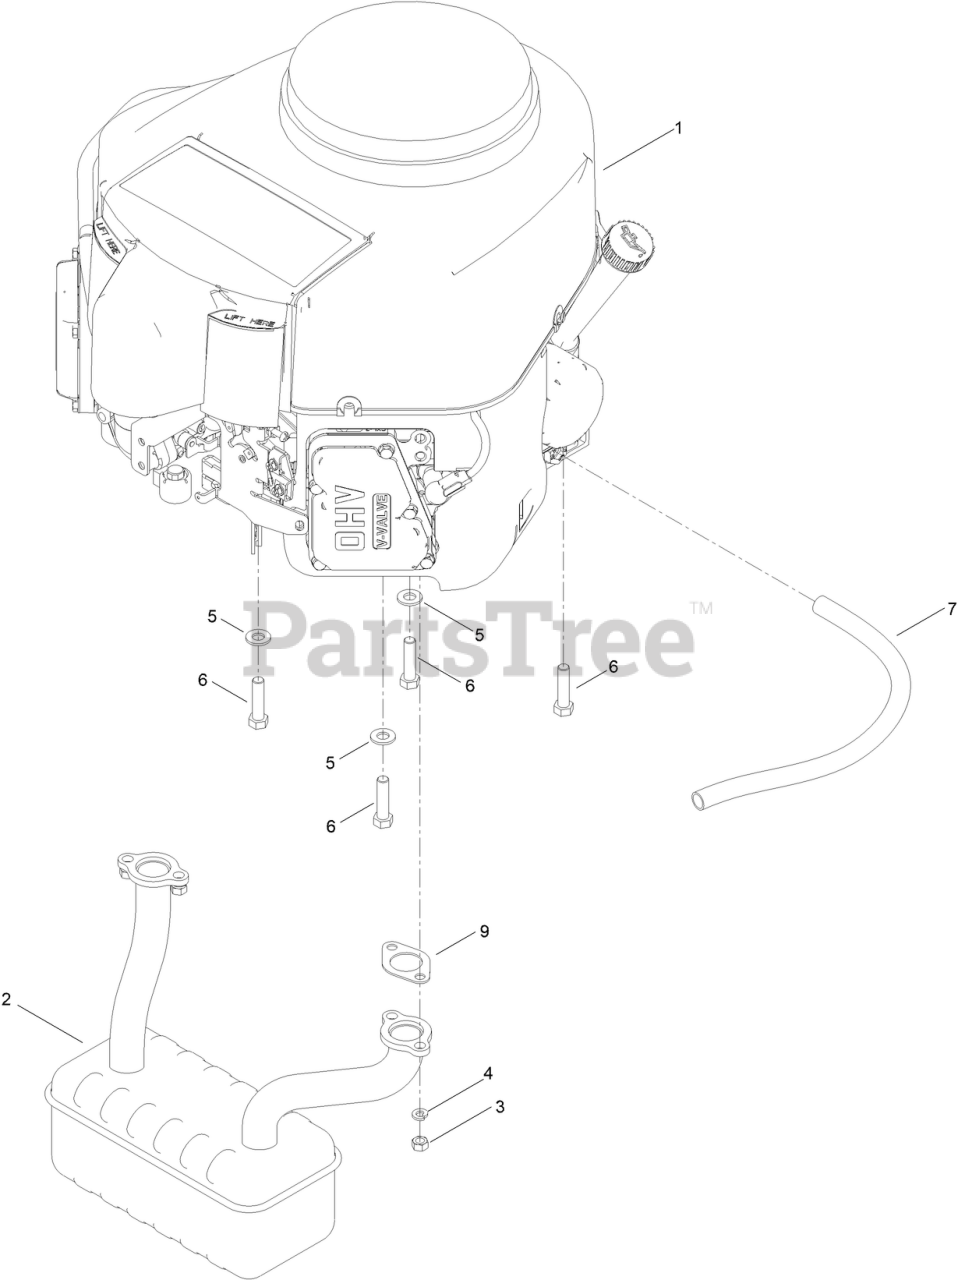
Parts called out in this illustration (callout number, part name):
2	MUFFLER
4	WASHER-LOCK
5	WASHER-FLAT
6	BOLT-HH
7	TUBE-DRAIN, OIL
9	GASKET-EXHAUST
